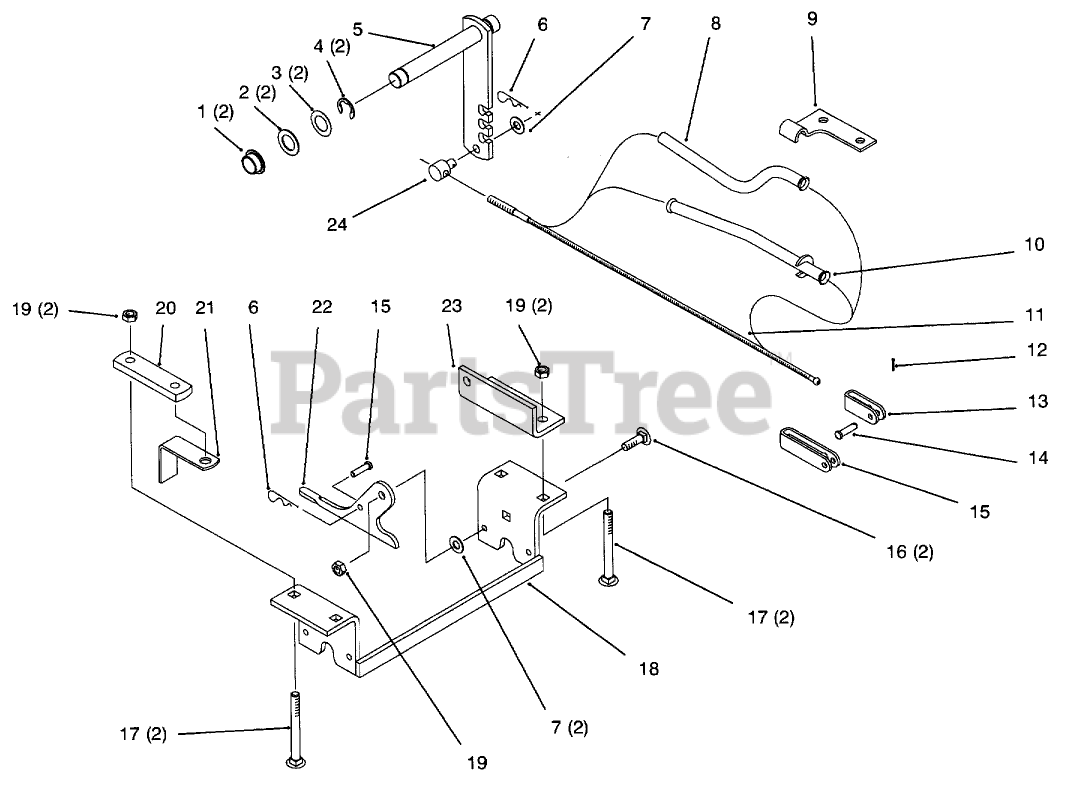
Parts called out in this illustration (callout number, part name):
1	BUSHING-BRONZE
2	WASHER
3	WASHER-SHIM
4	E-RING
5	ASSY LEVER R
6	PIN-HAIR
7	WASHER-FLAT
8	TUBE-CONDUIT R
9	CLAMP-CONDUIT R
10	TUBE ASSY COMPLET R
11	CABLE
12	PIN-COTTER
13	CLEVIS-SHORT
14	PIN-CLEVIS
15	CLEVIS-LONG
16	BOLT-CARR
17	SCREW-CARR
18	Bracket
19	NUT-HEX
20	BRACKET-REAR LINK MOUNTING
21	SPACER-BRACKET
22	PLATE-LATCHING
23	LINK-BRACKET R
24	TRUNNION-CLUTCH ROD
